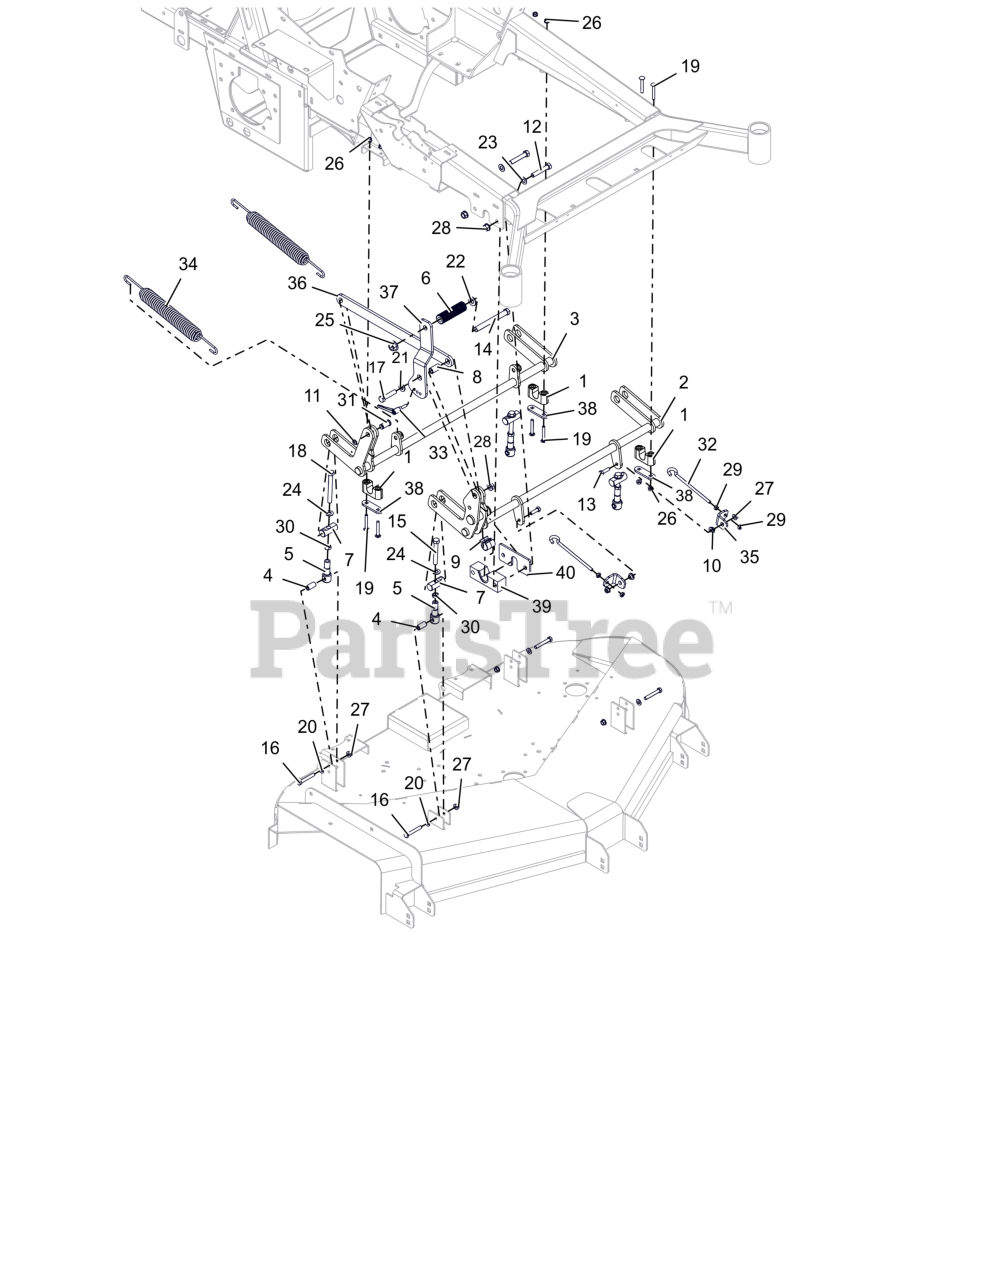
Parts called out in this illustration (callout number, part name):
1	ASM-BUSHING, DECK LIFT
2	WLDMT, FRONT DECK LIFT (BLACK)
3	WLDMT, REAR DECK LIFT (BLACK)
4	SPACER, DECK LEVELING
5	LINK, DECK LIFT FORMED
6	ROD, FOOT PEDAL (BLACK)
7	PIN, DECK LIFT
8	SPCR, SLV .531x.75x1.449
9	BUSHING, SHAFT
10	BSHG-FLG .385X.500X.875X.406
11	RG-RTNG-EXT .625X.050
12	BLT,HEX .50-13X2.75 G5 ZCC
13	BLT, HEX .38-16X1.25 G5 ZCC
14	BLT, HEX .62-11X5.50 G5 FBP
15	BLT, HEX 0.5-13X3.5F GR5 ZCC
16	BLT, HEX .38-16X2.50 G8 ZCC
17	BLT, HEX .50-13X2.25 G5 ZCC
18	BLT, HEX 0.5-13X4.5S GR5 ZCC
19	BLT, RHSSN.31-18X2.25 G5 ZCC
20	WSHR,FLT .406X.812X.065 ZCC
21	WSHR,FLT .531X1.062X.095 ZCC
22	WSHRFLT 5/8SAE CARBHARD FBP
23	WSHR, FLT .531X1.00X.063 ZCC
24	WSHR, FLT .557X1.040X.102 ZCC
25	NUT,FLG-TOP LK .625-11 FBP
26	NUT,LK-CTR-FLG .31-18 GF ZCC
27	NUT-LK-CTR-FLG .375-16 GF ZCC
28	NUT-LK-CTR-FLG .500-13 GG ZCC
29	NUT-JAM .375-16 G2 ZCC
30	NUT-JAM .500-13 G2 ZCC
31	PIN, CLEVIS .625 SNAP RING
32	BOLT, .38-16X6.00 .62 DIA EYE
33	HANDLE, CLAMPING
34	SPRG, DECK LIFT
35	BRKT, SPRING ANCHOR (BLACK)
36	LINK, DECK LIFT (BLACK)
37	ARM, ADJUSTABLE FOOT PEDAL (BLACK)
38	PLATE, PT600 BEARING SUPPORT (BLACK)
39	BUSHING, DECK LIFT
40	PLATE, SHAFT RETAINER (RED)
